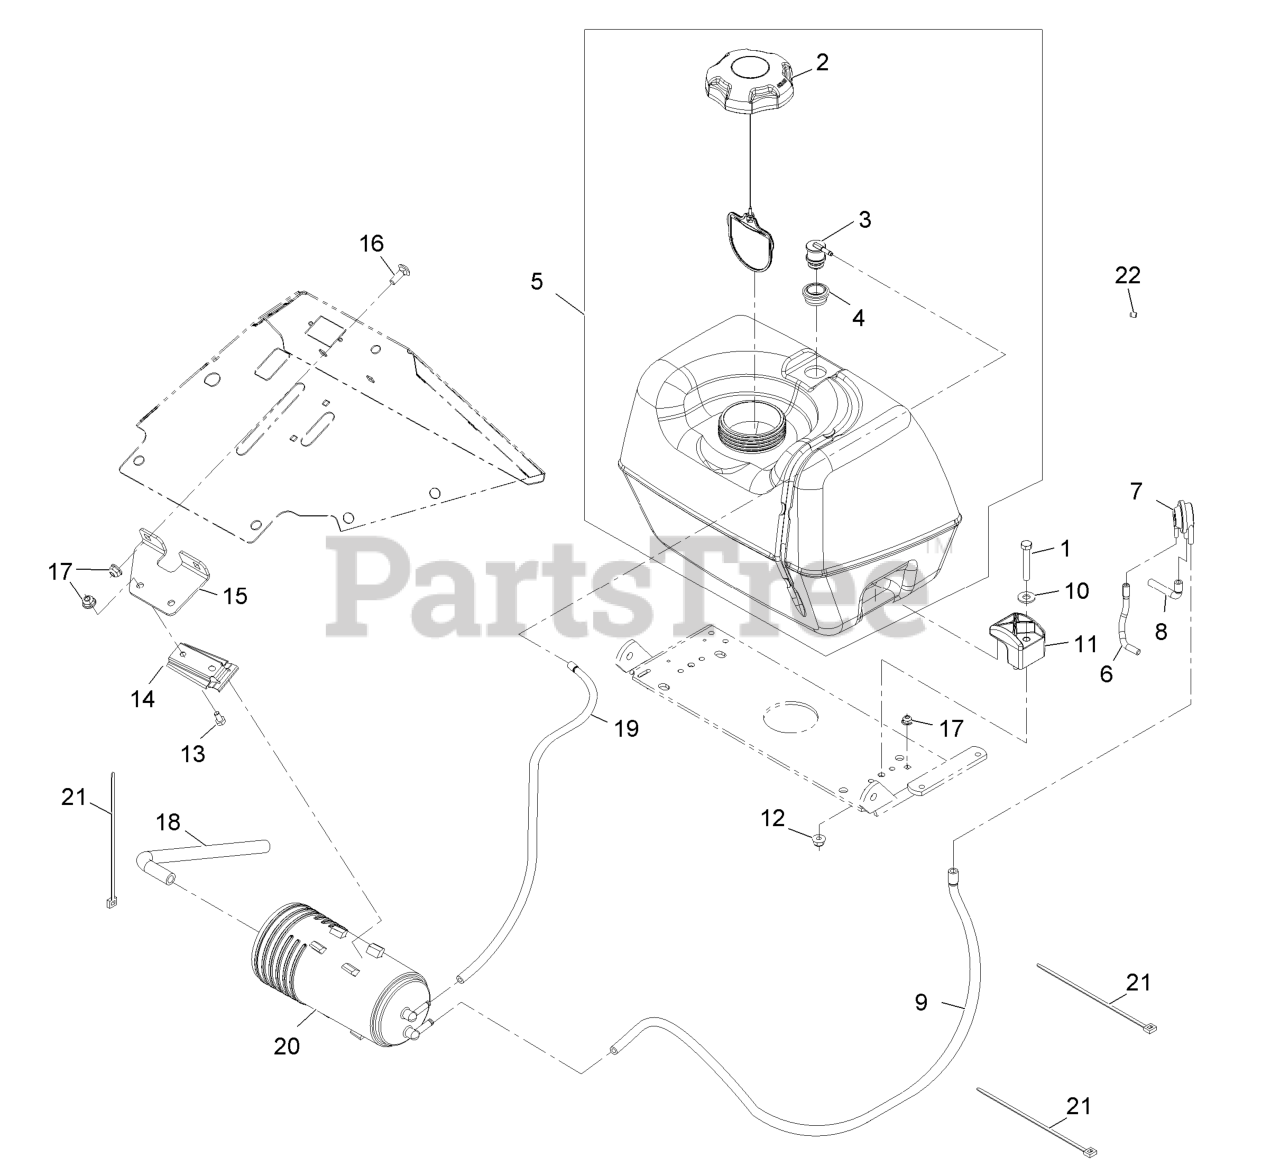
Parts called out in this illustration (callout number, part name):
1	SCREW-HH
6	HOSE-VENT, FORMED
7	VALVE-CONTROL, VACUUM
8	HOSE-VENT, FORMED
9	HOSE-VENT, FORMED
10	WASHER-FLAT
12	NUT-HF, NI
13	SCREW-HH
14	BRACKET-CANISTER, CARBON
15	BRACKET-CANISTER, CARBON
16	BOLT-CARR
18	HOSE-VENT, CANISTER
19	HOSE-VENT
20	CANISTER-CARBON, 800CC
21	TIE-CABLE
22	PLUG-PORT
